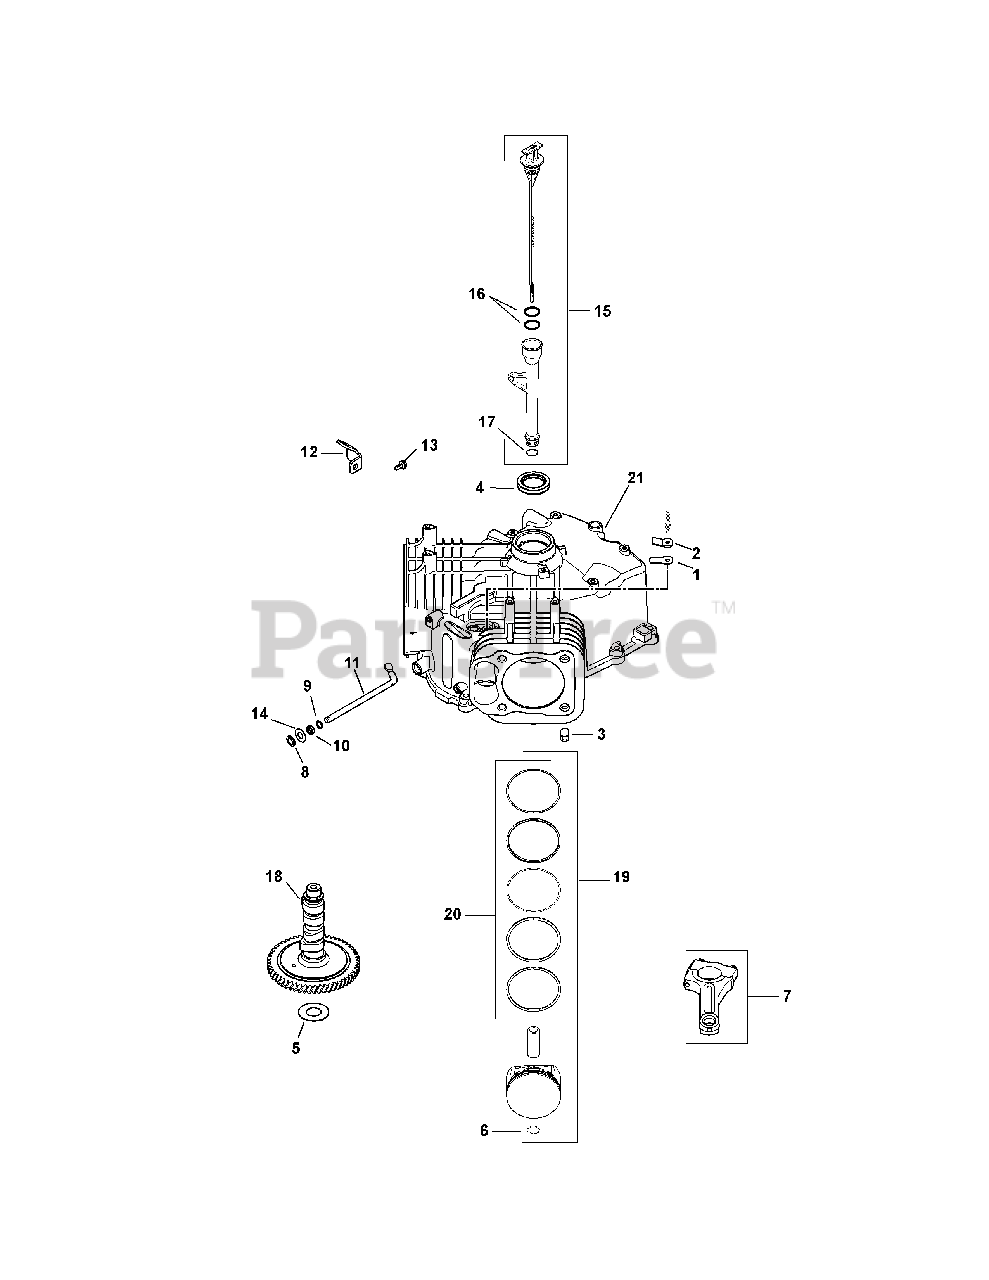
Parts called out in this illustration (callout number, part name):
1	Breather Reed
2	Breather Reed Retainer
4	Oil Seal, 1.78 x 1.26
5	Camshaft Shim (White, .028)
5	Camshaft Shim (Blue, .03)
5	Camshaft Shim (Red, .032)
5	Camshaft Shim (Yellow, .034)
5	Camshaft Shim (Green, .036)
5	Camshaft Shim (Gray, .038)
5	Camshaft Shim (Black, .04)
6	Piston Pin Retainer
7	Connecting Rod (STD)
8	Ring Retainer
9	Flat Washer, 11/32
10	Governor Cross Shaft Seal
11	Governor Cross Shaft
12	Oil Fill Tube Bracket
13	Flange Screw, M5 x .8 x 13
14	Flat Washer, 9mm
15	Dipstick & Tube Kit
17	Lower Oil Fill Tube O-Ring
18	Camshaft Assembly
19	Piston Kit w/ Ring
19	Piston Kit w/ Ring (0.25) 83mm
19	Piston Kit w/ Ring (0.08) 83mm
20	Ring Set, Piston STD
20	Ring Set, Piston (.08)
20	Ring Set, Piston (.25)
21	Crankcase (Use Short Block)
